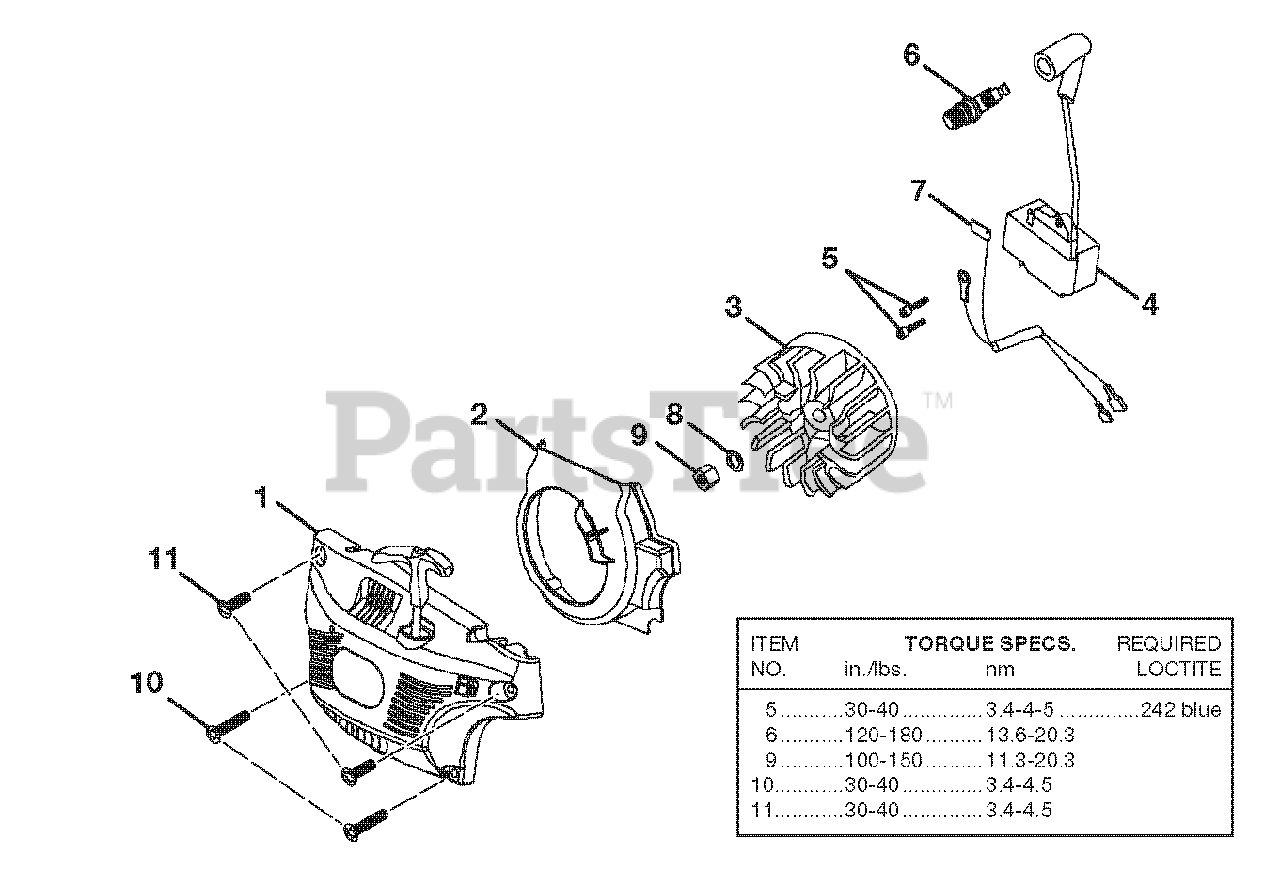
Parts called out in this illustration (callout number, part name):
1	STARTER COVER ASSY., W/EYELET
2	BAFFLE
3	ROTOR W/STARTER PAWL
4	IGNITION KIT
5	SCREW (8-32 x 5/8 in.)
6	SPARK PLUG
7	IGNITION SWITCH HARNESS
8	WASHER
10	SCREW (10-14 x 7/8 in.)
11	SCREW (10-14 x 5/8 in.)
